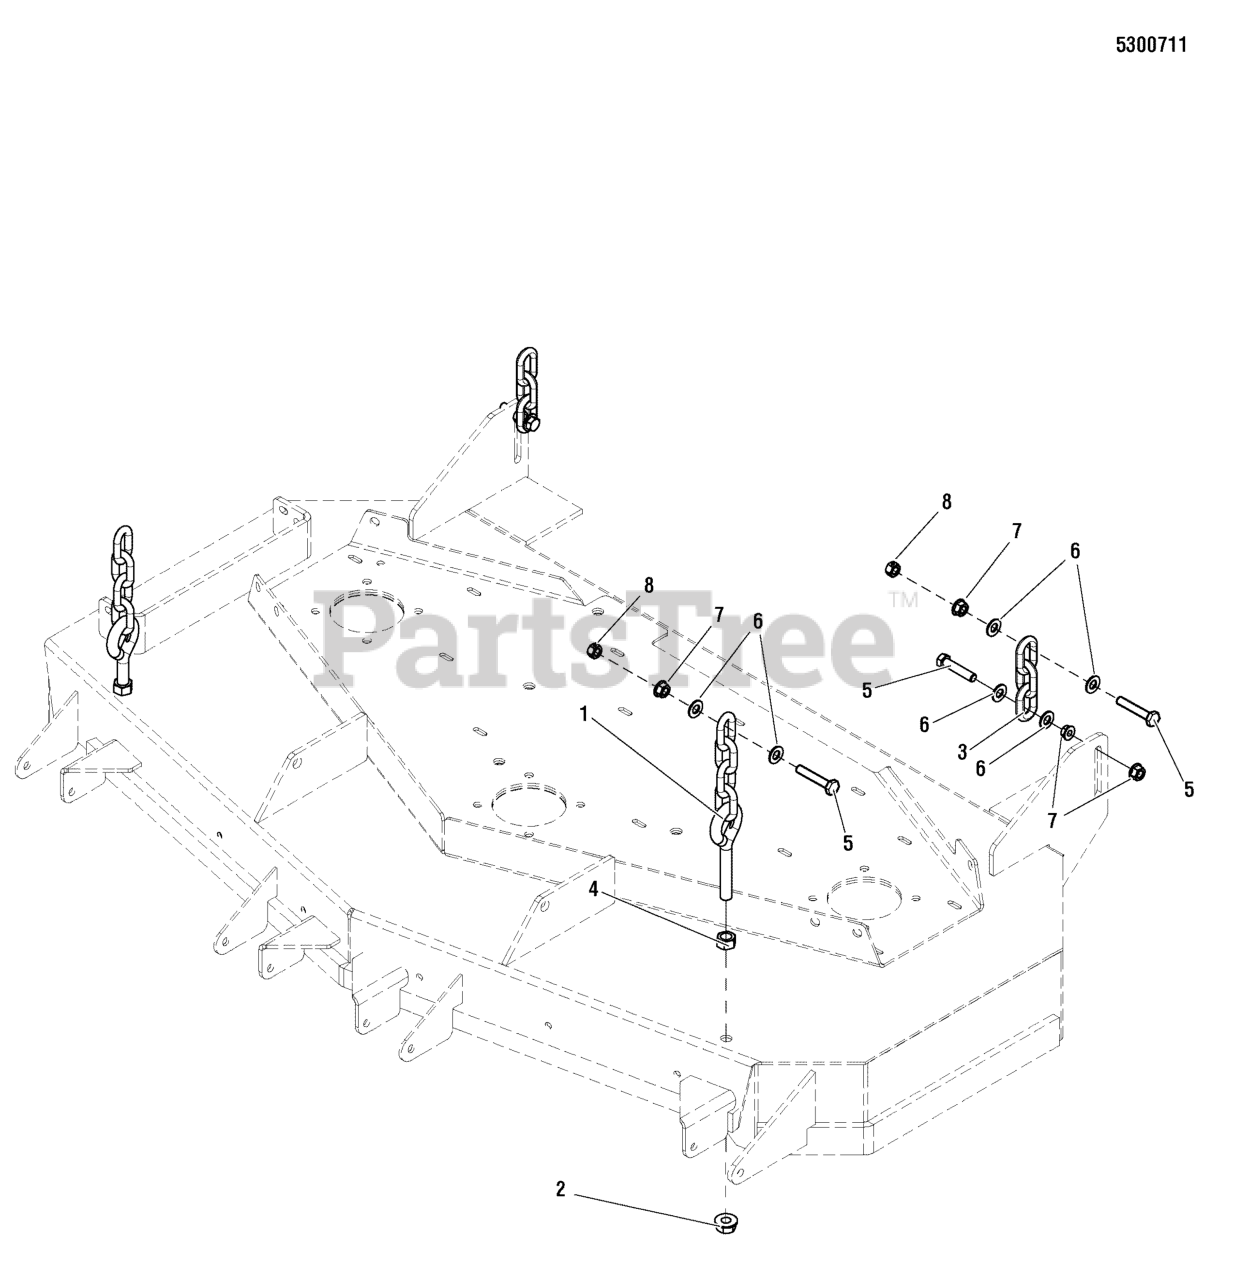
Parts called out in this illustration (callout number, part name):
1	HANGER, FRONT DECK - 4 LINK, 5.5" EB
2	NUT, Hex Flange, Nylock, 1/2-13
3	CHAIN, 5/16" GD30, 3 LINKS
4	NUT, 1/2-13 HEX
5	BOLT, 3/8-16 X 1-3/4" GD5 CZ
6	WASHER, 3/8 SAE
7	NUT, 3/8-16 HEX SERRATED FLANGE
8	NUT, 3/8-16 HEX SIDE LOCK
